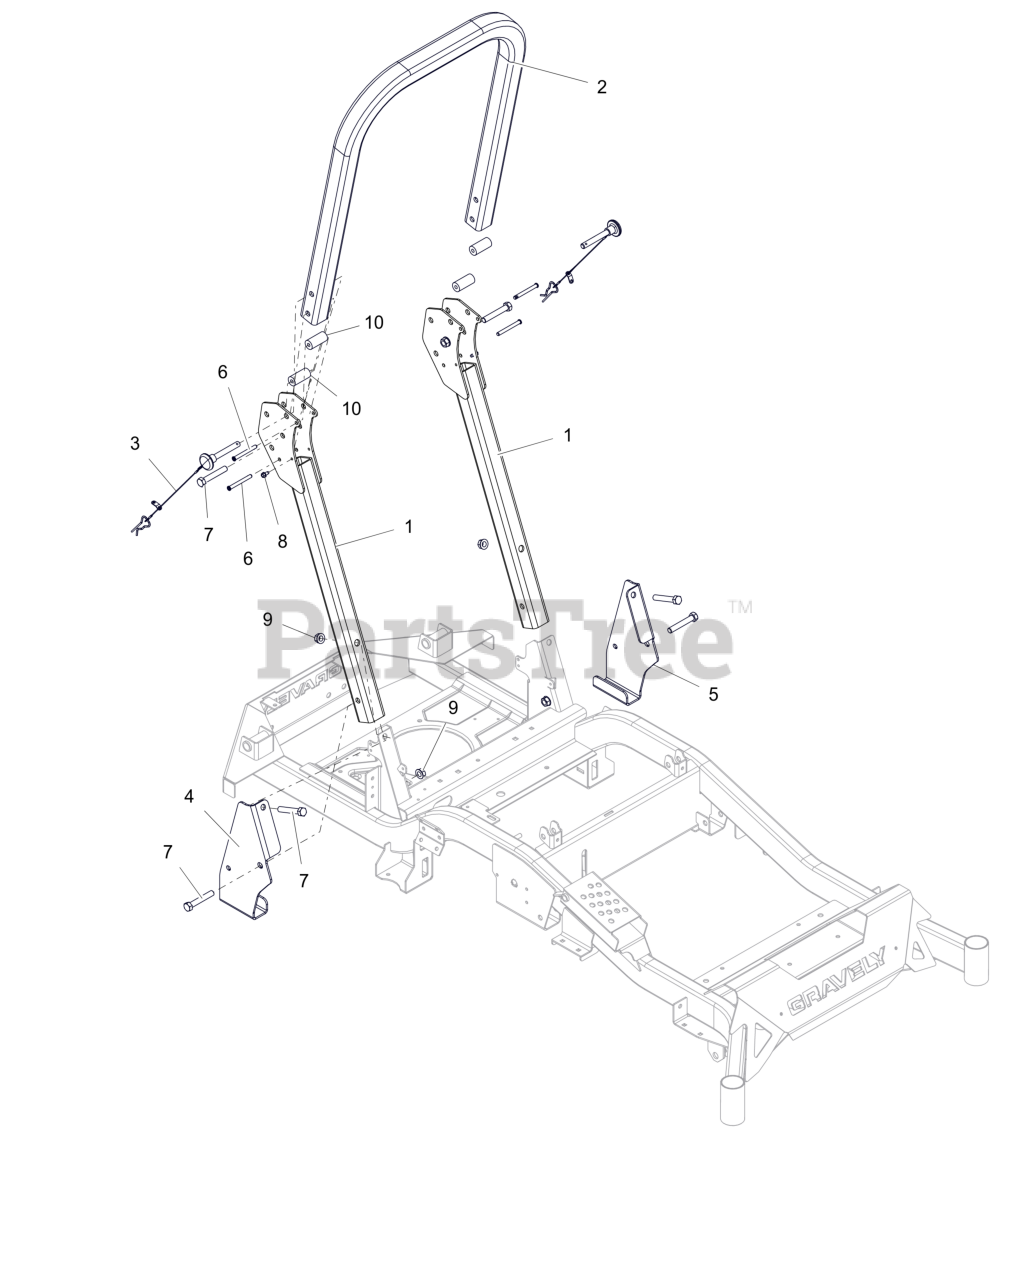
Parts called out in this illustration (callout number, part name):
1	ROPS, REPLACEMENT
2	HOOP, PT Z & ZX ROPS
3	PIN, ROPS W/LANYARD
4	BRKT, ROPS SUPPORT - RH
5	BRKT, ROPS SUPPORT -LH
6	PIN, SLIC .312 X 2.570
7	BLT, HEX .50-13X3.00 G5 ZCC
8	SCR-TAP .25-20X.50 HWH ZCC
9	NUT-LK-CTR-FLG .500-13 GG ZCC
10	BUMPER, ROPS ANTI-VIBRATION
